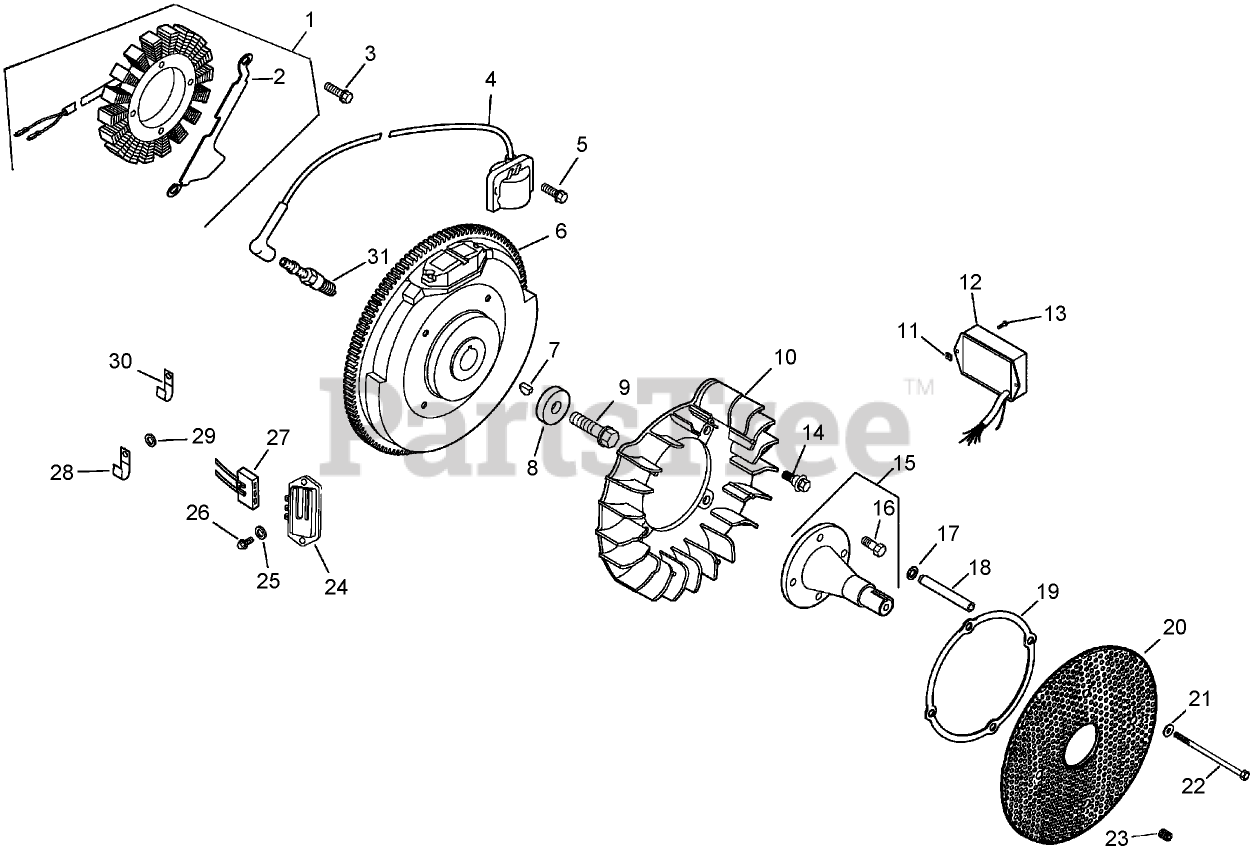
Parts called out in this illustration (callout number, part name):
1	Stator Kit (Includes 2)
2	Bracket-Wire, Stator
3	SCREW-THREAD FORMING (M5X0.8X25)
4	Module-Ignition
5	SCREW-FLANGE, THREAD FORMING (M5X.8X20)
6	Flywheel
7	KEY (3/16 X 5/8)
8	WASHER-FLAT (13/32)
9	SCREW-FLANGE (M10X1.5X45)
10	Fan
11	NUT-PLASTIC
12	Module-Advance, Speed
13	SCREW-PPH (11-16X1/2)
14	BOLT-SHOULDER (M6x1.0x16)
15	Front Drive Shaft Kit (Includes 16)
16	Screw-HF (M8x1.25x25)
17	WASHER-FLAT (1/4)
18	Spacer
19	Ring-Support
20	Screen-Grass
21	Washer-Spring (10MM)
22	Screw-HH (M6x1.0x100)
23	Screw-Set (10-24X.25)
24	Rectifier-Regulator
25	WASHER-FLAT (.188)
26	SCREW-PHL HD (11-16X.88)
27	Connector (3 contact)
28	CLAMP-INSULATED
29	WASHER-FLAT (1/4)
30	CLIP-CABLE
31	SPARK PLUG (PRO SERIES)
